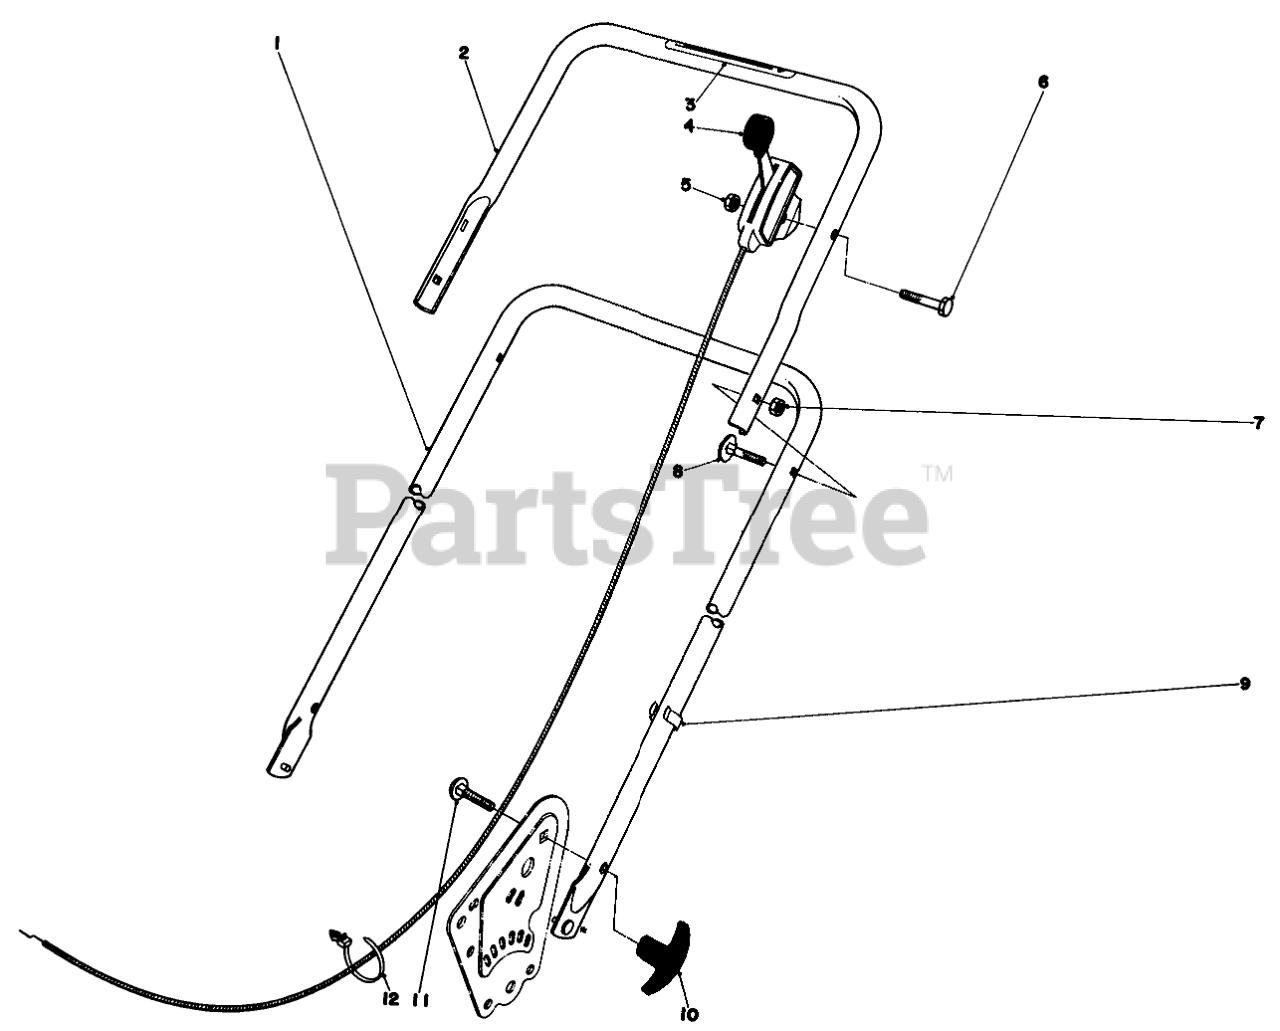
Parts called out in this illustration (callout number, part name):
1	Lower Handle
2	Upper Handle
3	Decal
4	Throttle Control
5	NUT-LOCK
6	SCREW-HH
7	Nut
8	HANDLE SCREW
11	BOLT-CARR
12	TIE-MOUNT, PUSH
